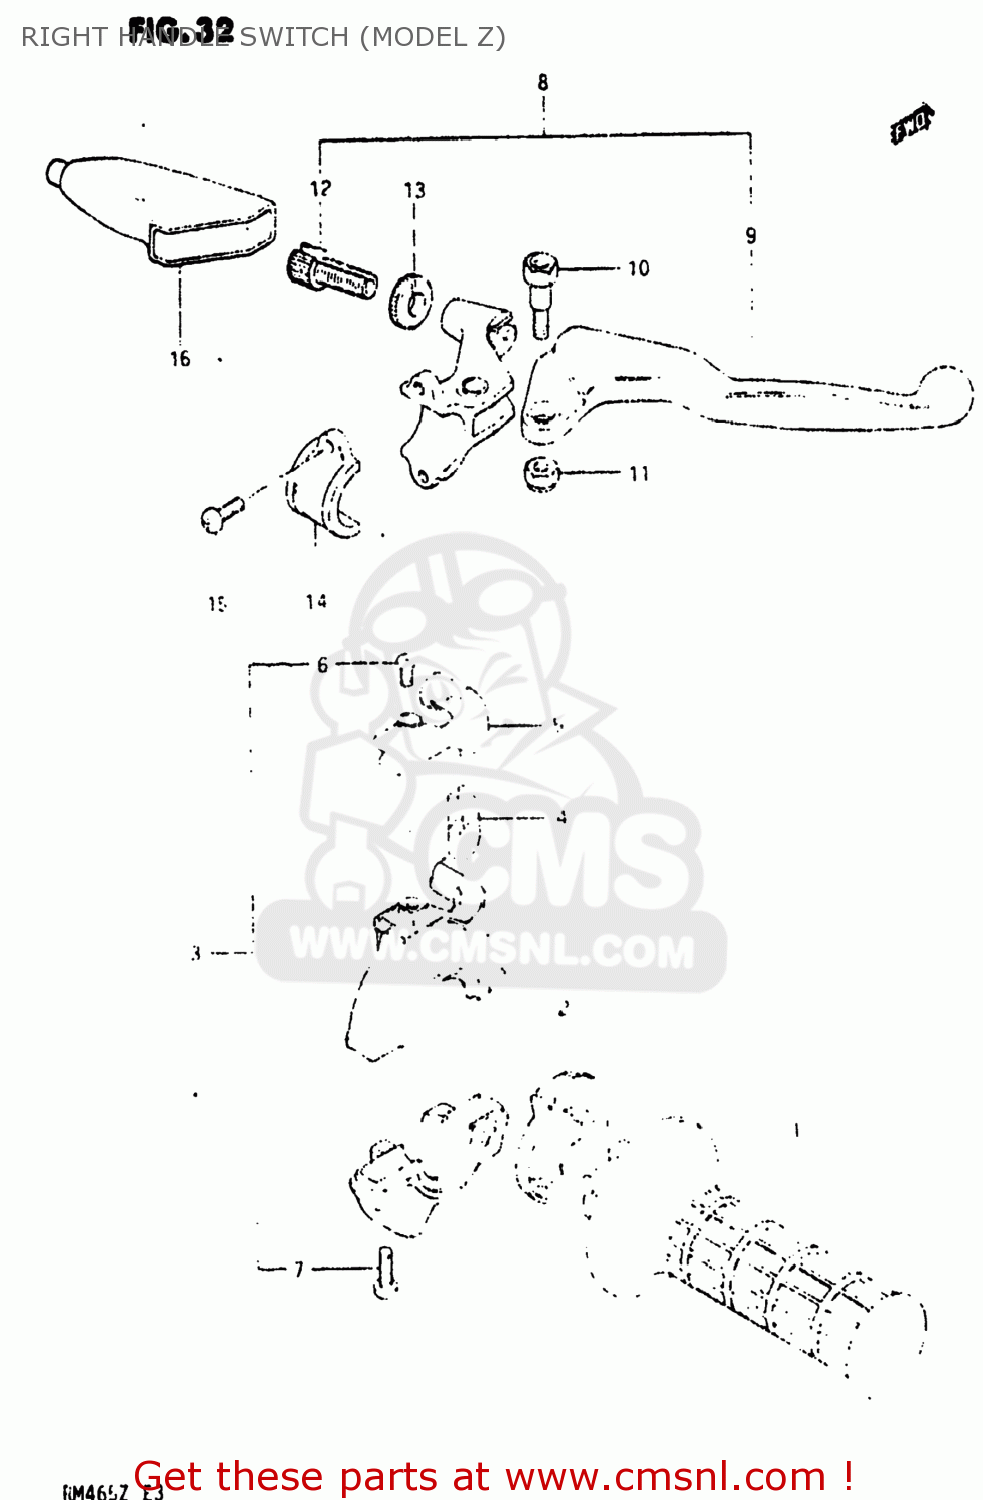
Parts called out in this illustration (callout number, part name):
1	CASE ASSEMBLY,THROTTLE
2	ROTOR,THROTTLE GRIP
3	CASE ASSEMBLY,THROTTLE
4	GUIDE PIECE,THROTTLE
5	COVER,THROTTLE CASE
6	SCREW
7	SCREW
8	LEVER ASSEMBLY,BRAKE
9	LEVER,BRAKE
10	BOLT,LEVER
11	NUT 6MM
12	ADJUSTER,CABLE
13	NUT,CABLE ADJUSTER
14	BRACKET,CLUTCH LEVER HOLDER
15	SCREW
16	COVER,CLUTCH LEVER
